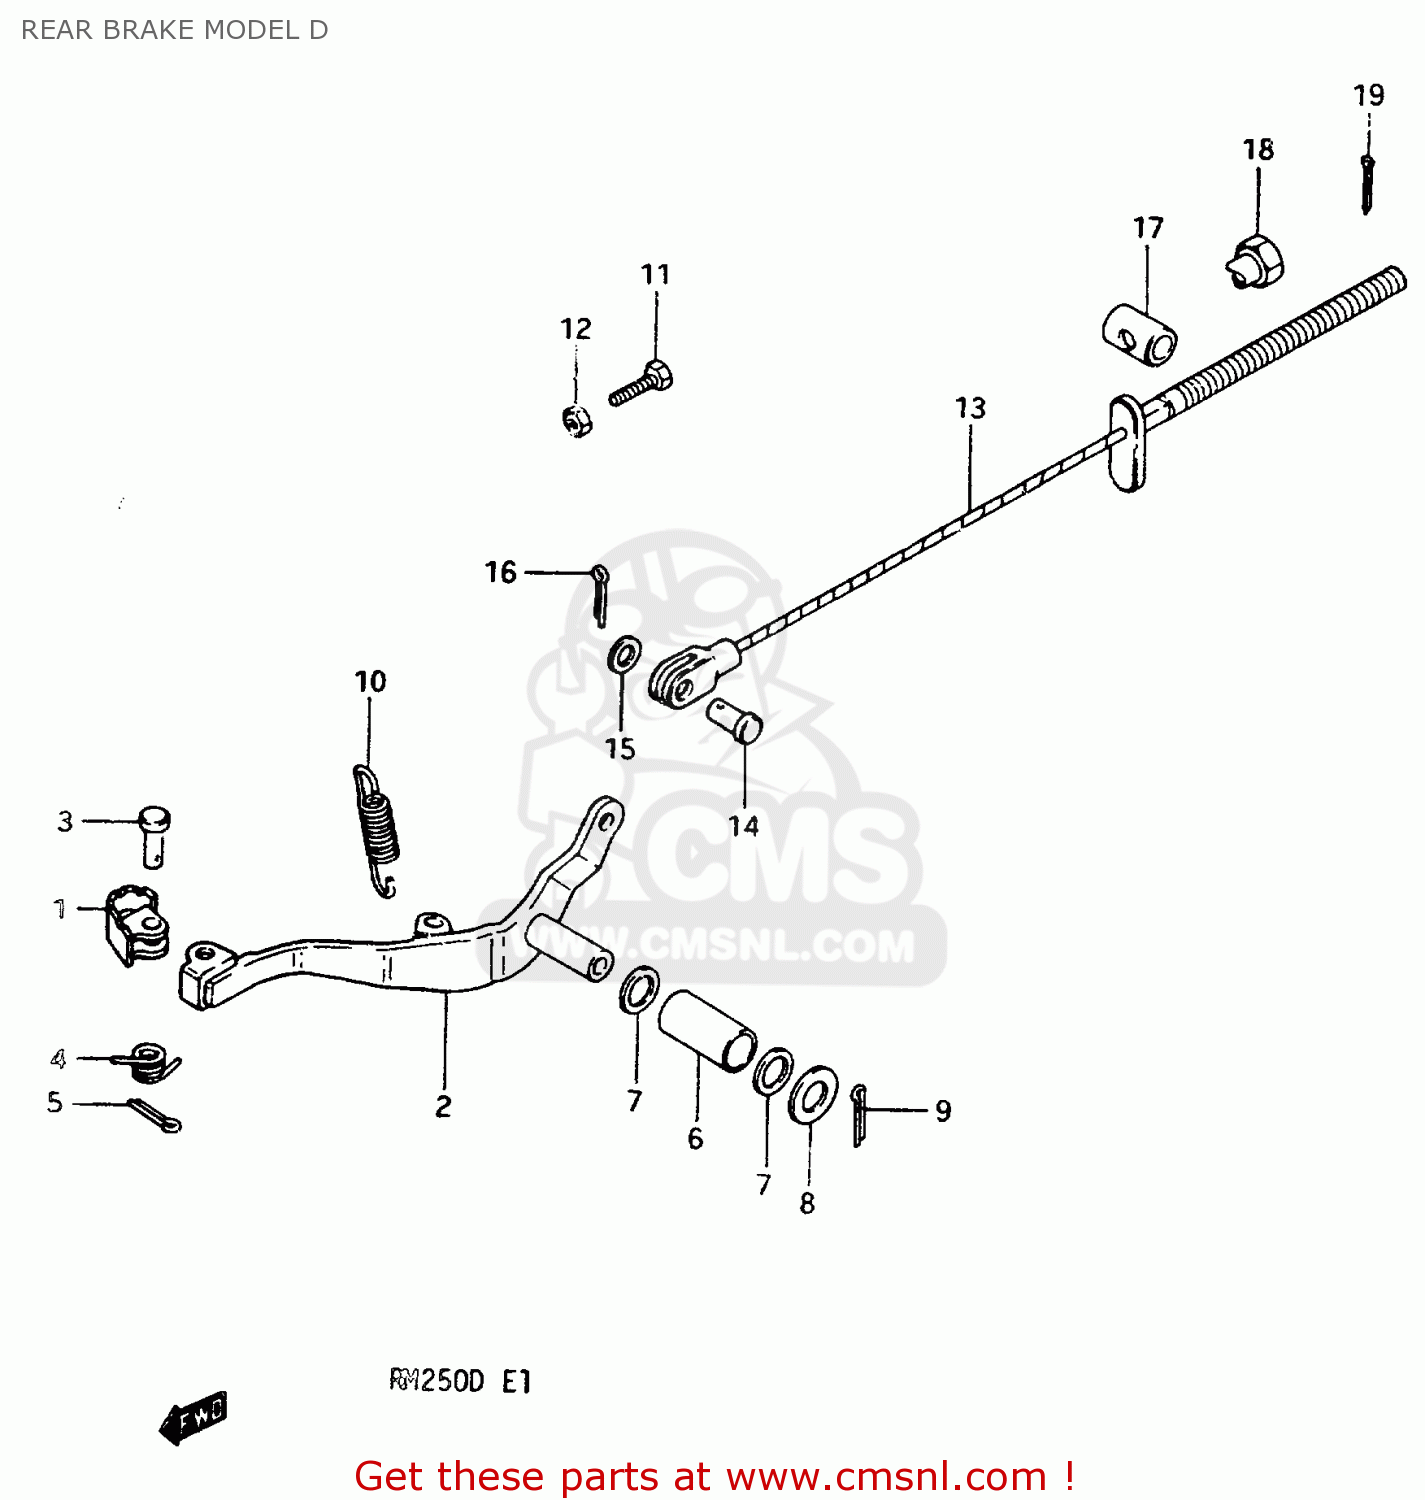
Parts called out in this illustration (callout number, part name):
1	PEDAL,BRAKE
2	ARM,BRAKE PEDAL
3	PIN
4	SPRING
5	PIN
6	BUSHING
7	O RING(D:2.2,ID:11.8)
8	WASHER
9	PIN 30X20
10	SPRING
11	SCREW(6X23)
12	NUT
13	CABLE,RR BRAKE
14	PIN(L:17.5)
15	WASHER
16	PIN 20X20
17	PIN
18	NUT (6MM)
19	PIN
